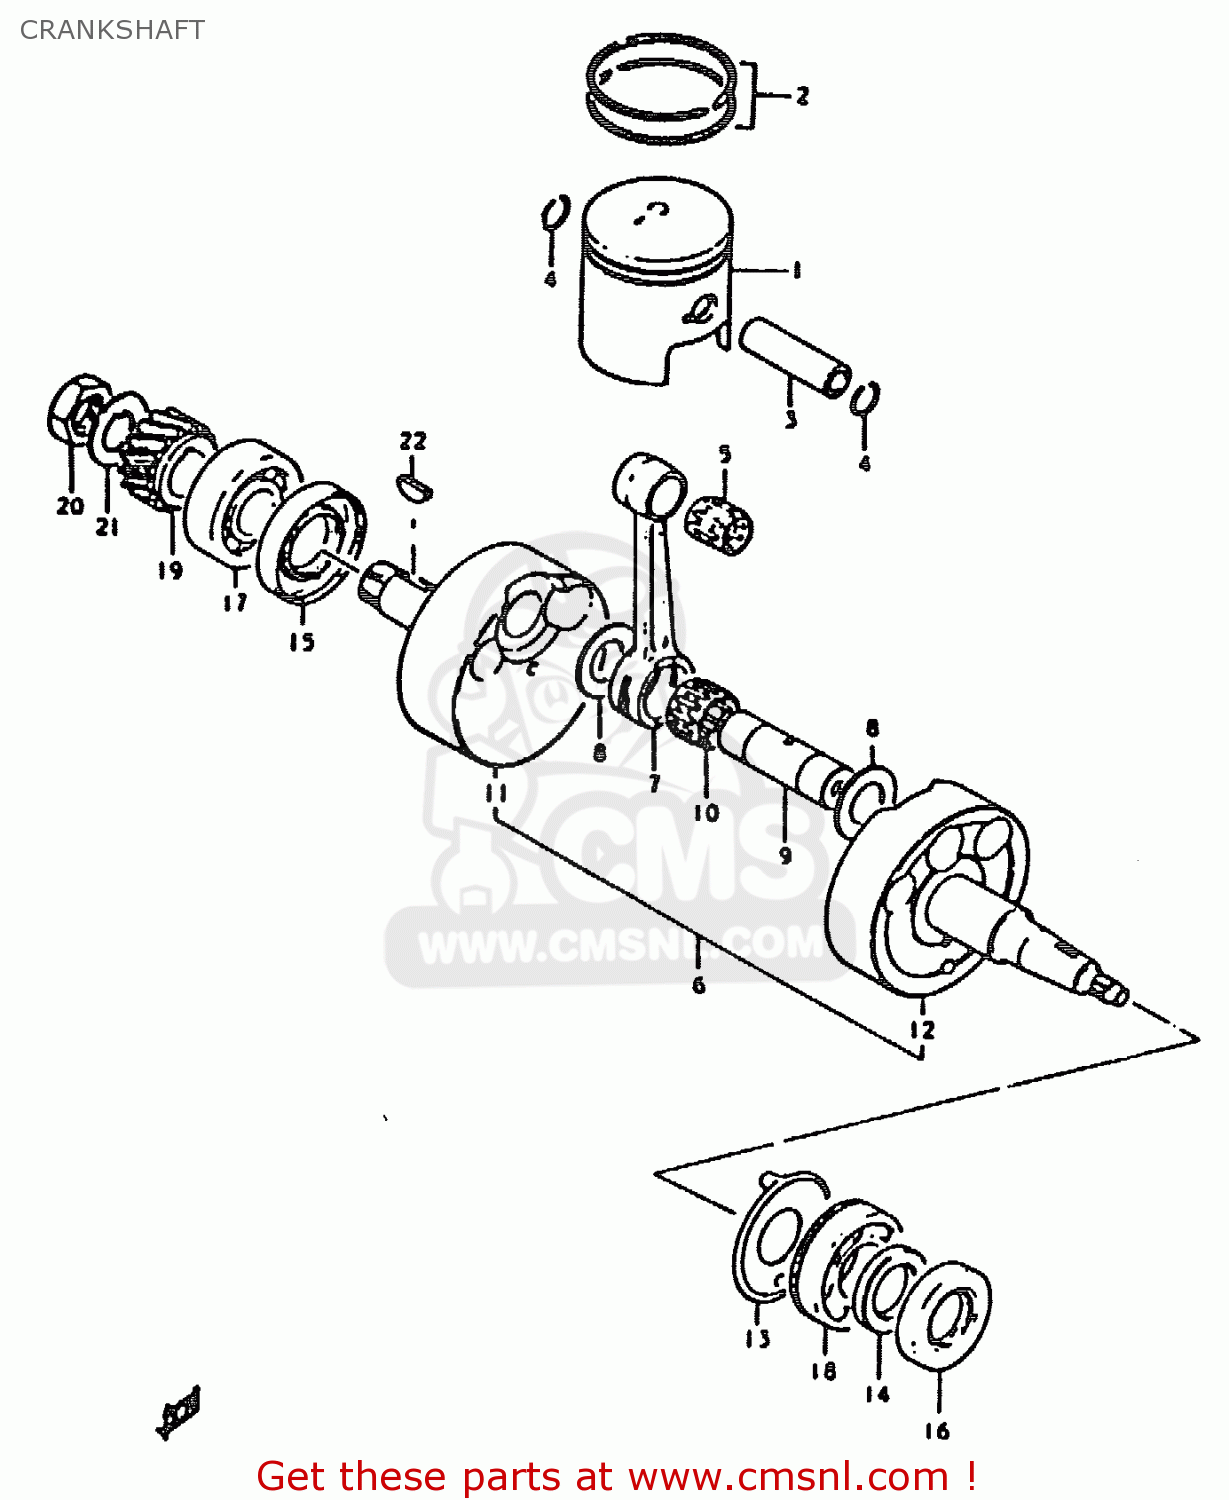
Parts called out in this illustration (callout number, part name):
1	PISTON
2	RING SET,PISTON
3	PIN,PISTON
4	RING,SNAP 16MM
5	BEARING
6	CRANKSHAFT ASSEMBLY
7	ROD, CONNECTING
8	WASHER(22X35X1)
9	PIN,CRANK
10	BEARING 22X28X16
11	CRANKSHAFT,R
12	CRANKSHAFT,LEFT
13	PLATE,CSHAFT OIL GUIDE
14	SPACER(25X34X4.5)
15	SEAL,OIL(26X52X8)
16	OIL SEAL
17	BEARING
18	BEARING(25X62X17)
19	GEAR,PRIMARY DRIVE
20	NUT
21	WASHER
22	KEY
